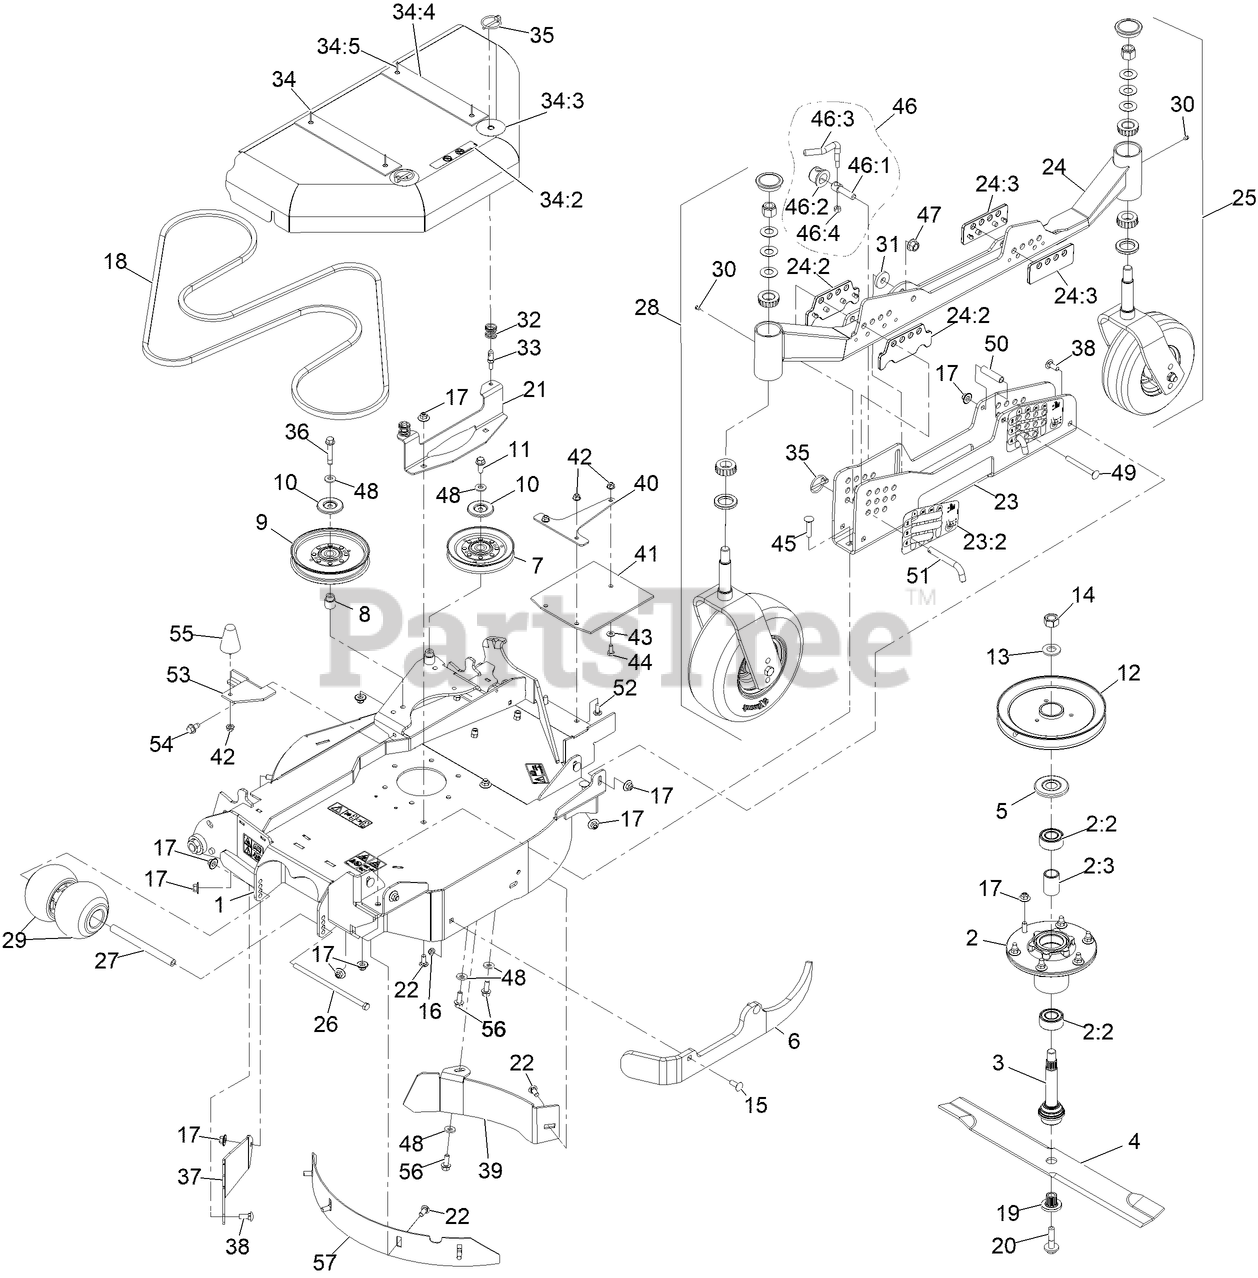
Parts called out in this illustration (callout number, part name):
1	ASM-DECK, LH WING 96E
2	ASM-CUTTER HSG
2:2	BEARING-3205 TRASHGUARD
2:3	SPACER-BEARING
3	ASM-SPINDLE AND SEAL
5	GUARD-BEARING, TOP
6	BUMPER-96 LH
7	IDLER-V
8	BUSHING-IDLER
9	IDLER-PULLEY
10	SHIELD-DUST
11	SCREW-HHF 3/8-16 X 1
12	SHEAVE-SINGLE 96RD
14	NUT-HEX
15	SCREW-CARR
17	Nut-Nyloc 3/8-16 Flg
19	BUSHING,SPLINED
20	SCREW,SEMS 1/2-20 X 2.19
21	BRACKET-SHIELD MOUNT, OUT
22	BOLT-CARR
23	ASM-CHANNEL, HOC LH
23:2	DECAL-HEIGHT OF CUT-LH
24	ASM-LH GAUGE WHEEL ARM
24:2	PLATE-GUIDE, REAR
24:3	PLATE-GUIDE, FRONT
25	Caster/Wheel ASM
26	SCREW-HH
27	SPACER-WHEEL
29	ROLLER-SCALP, ANTI
33	PIN, SPRING
34	ASM-Wing Shield LH
34:2	DECAL-NO STEP
34:3	DECAL-SCRATCH COVER
34:4	Plate-Uhmw 2"
34:5	Rivet-Pop
35	PIN-LYNCH
36	SCREW-HHF
37	PLATE-FILL, LH DECK
38	BOLT-CARR
39	BAFFLE-BLOCK, LH WING
40	SUPPORT-FLAP, LH
41	GUARD-TIRE, LH
42	NUT-HF, NI
43	WASHER-PLAIN
44	SCREW-HH
45	SCREW-CARR
46	LEVER ASM
46:1	SCREW-LOCK
46:2	CAP-LOCK
46:4	NUT-LOCK, NI
47	Nut-Lock 1/2-13
48	WASHER-BELLEVILLE
49	SCREW-CARR
51	PIN-HOC
52	BOLT-CARR
53	BRACKET-COVER RETAINER
54	SCREW-HWH
55	BUMPER-RUBBER
56	SCREW-HHF
57	BAFFLE-DEPTH, LH
